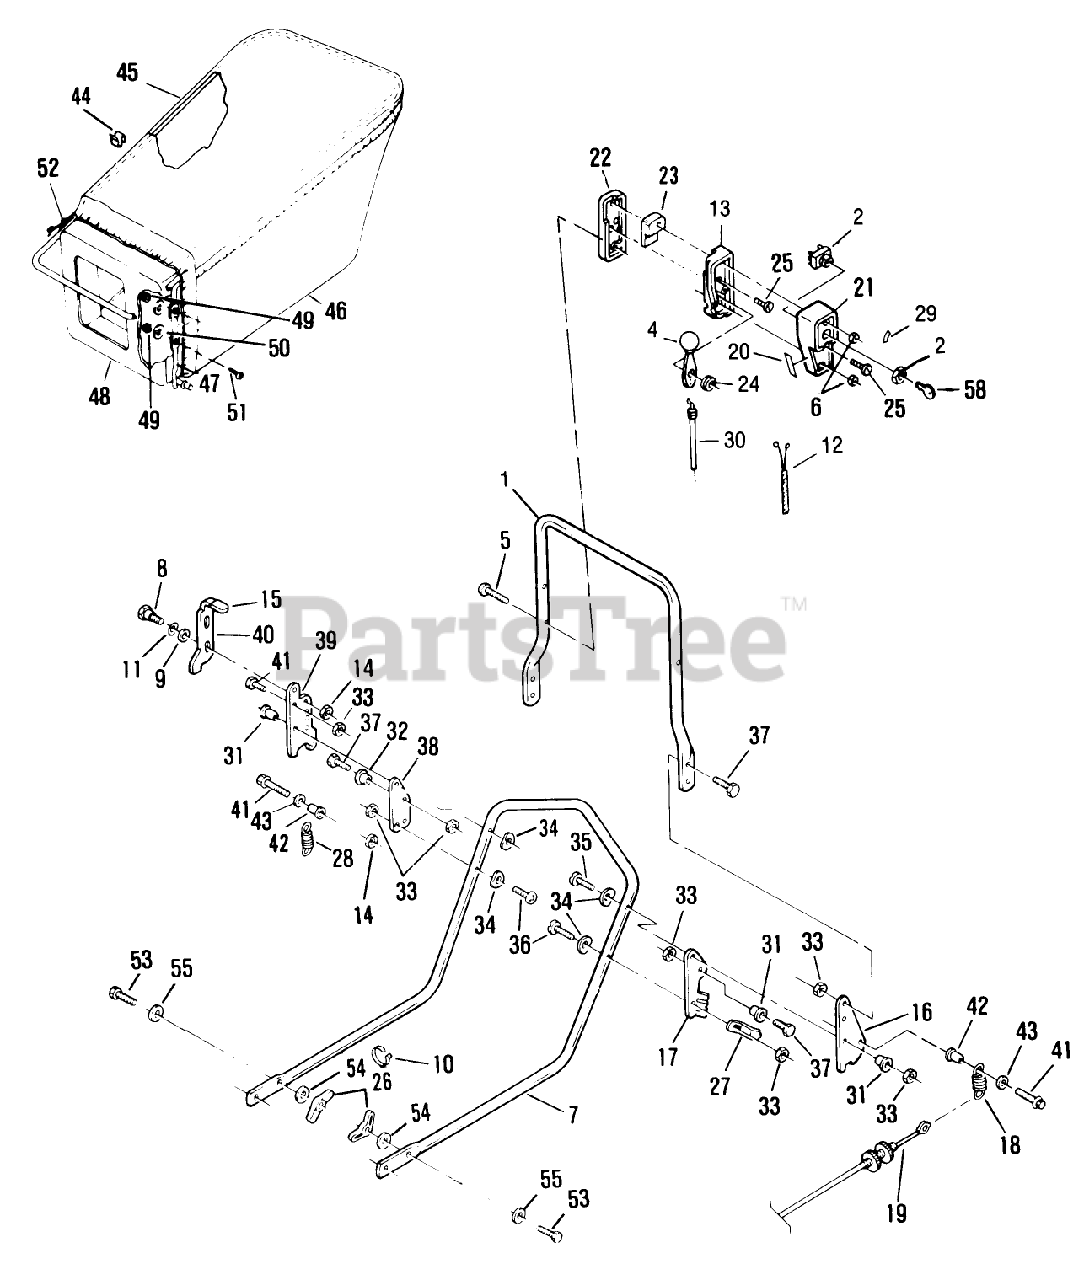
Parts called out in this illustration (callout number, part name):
1	612873 PLATED
4	LEVER&KNOB AY WES
5	SCREW
6	NUT C/LOCK E
8	BOLT RB&W
9	WASHER M
14	LOCKNUT E
15	KNOB (S&R)
18	SPRING
19	CABLE AY
24	WASHER-SPRING
25	SCREW
26	NUT-WING
29	Decal-Start
30	T/CABLE WESCON
33	NUT-LOCK F
34	WASHER-CURVED
35	SCREW LARSON
42	SPACER ROCKFORD
43	WASHER
44	S CLIP ARDEN
45	HANGER BAG TROX
48	BAG ADAPTOR PL
49	LOCKNUT E
50	WASHER
55	WASHER
